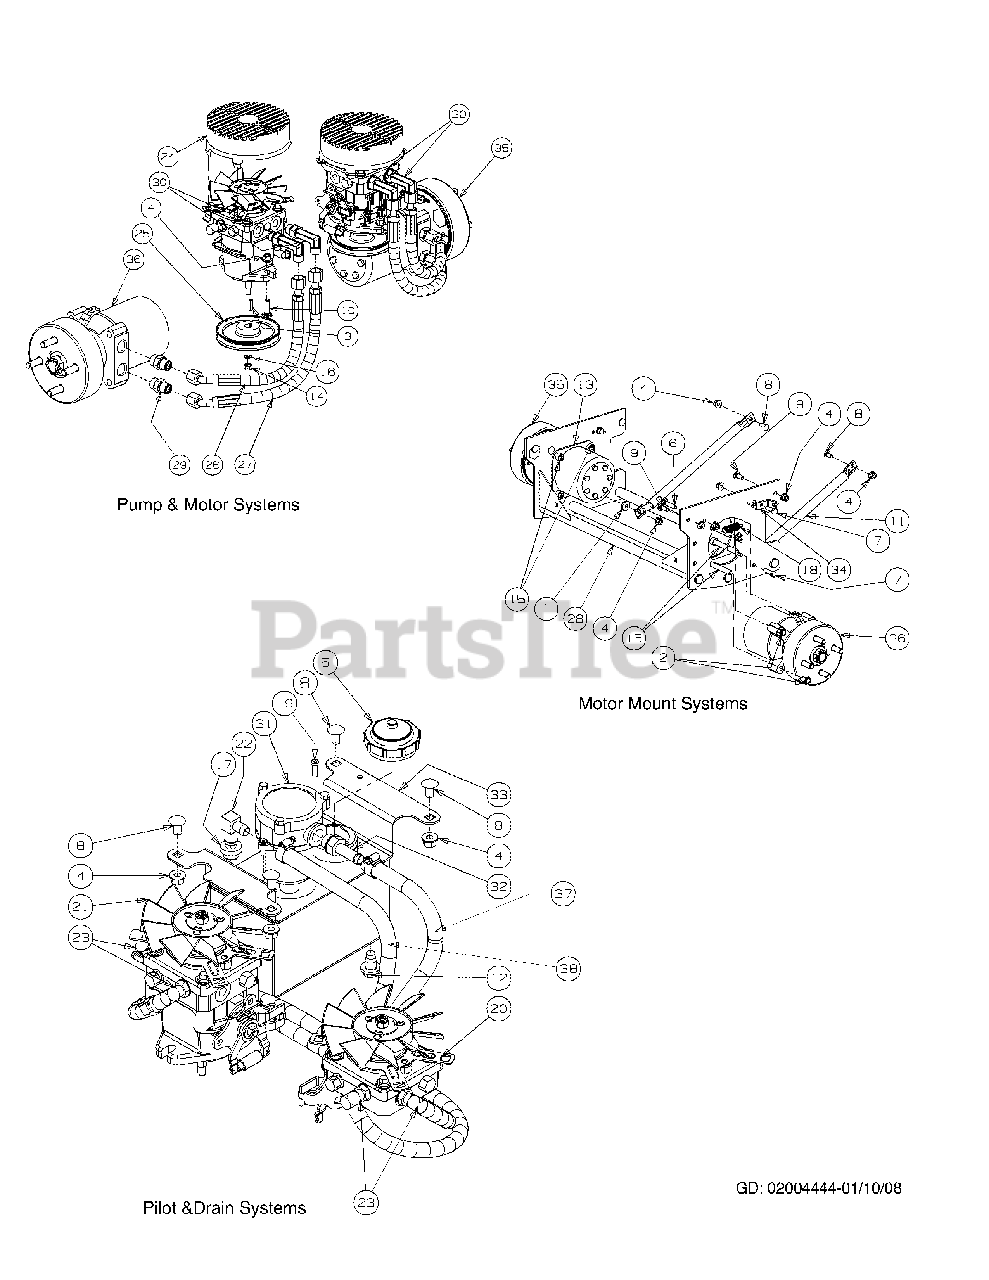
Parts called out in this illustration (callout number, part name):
1	Idler Washer
2	Lock Nut, Nylon Insert, 1/2-13
3	Key, 3/16" x 7/8"
4	Flange Lock Hex Nut, 3/8-16
5	Cap, Hydro Oil Tank
6	Hex Carriage Screw, 3/8-16, 1.75
7	Hex Cap Screw, 3/8 -16 x 1.25
8	Carriage Bolt, 3/8-16 x .75 LG.
9	Carriage Bolt, 3/8-16 x 1
10	Carriage Screw, 3/8-16 x 1.25
13	Hydro Wheel Motor Backup Plate
14	Hex Nut, 3/8-24
15	Socket Head Capscrew, 1/2-13; 3-1/2
16	Flat Washer, 3/8
17	Grommet Fitting, .54 ID x .78 OD
18	Spring Extension, .740 OD x 2.656
19	Socket Low Head Cap Screw, 1/4-20 x 0.75
20	Hydro Pump, BDP-12, RH
20	Kit, Fan
21	Hydro Pump, BDP-12, LH
21	Kit, Fan
22	Fitting Elbow Spur, 5/8 x 1/2
23	Fitting Elbow, 9/16 x 1/2
24	Fan Pump Shroud
25	Hydro Pump Pulley
26	Short Pressure Hose Assembly
27	Long Pressure Hose Assembly
30	Adaptor, 8 x 8
31	Hydraulic In-Tank Filter includes:
31	Replacement Filter
32	Fitting, 3/4 ORB x 1/2 Tube
33	Hydraulic Tank Assembly
34	Rear Cable Mounting Bracket
35	Hydro Motor, Left Hand Assembly w/ Brake & Drum
36	Hydro Motor, Right Hand Assembly w/ Brake & Drum
37	Hose Assembly, Pilot Includes:
37	Tee Fitting, 1/2
37	Hose Clamp, 1/2
37	Fuel Hose, .50 ID x .75 OD
38	Hose Assembly, Drain Includes:
38	Tee Fitting, 1/2
38	Hose Clamp, 1/2
38	Fuel Hose, .50 ID x .75 OD
